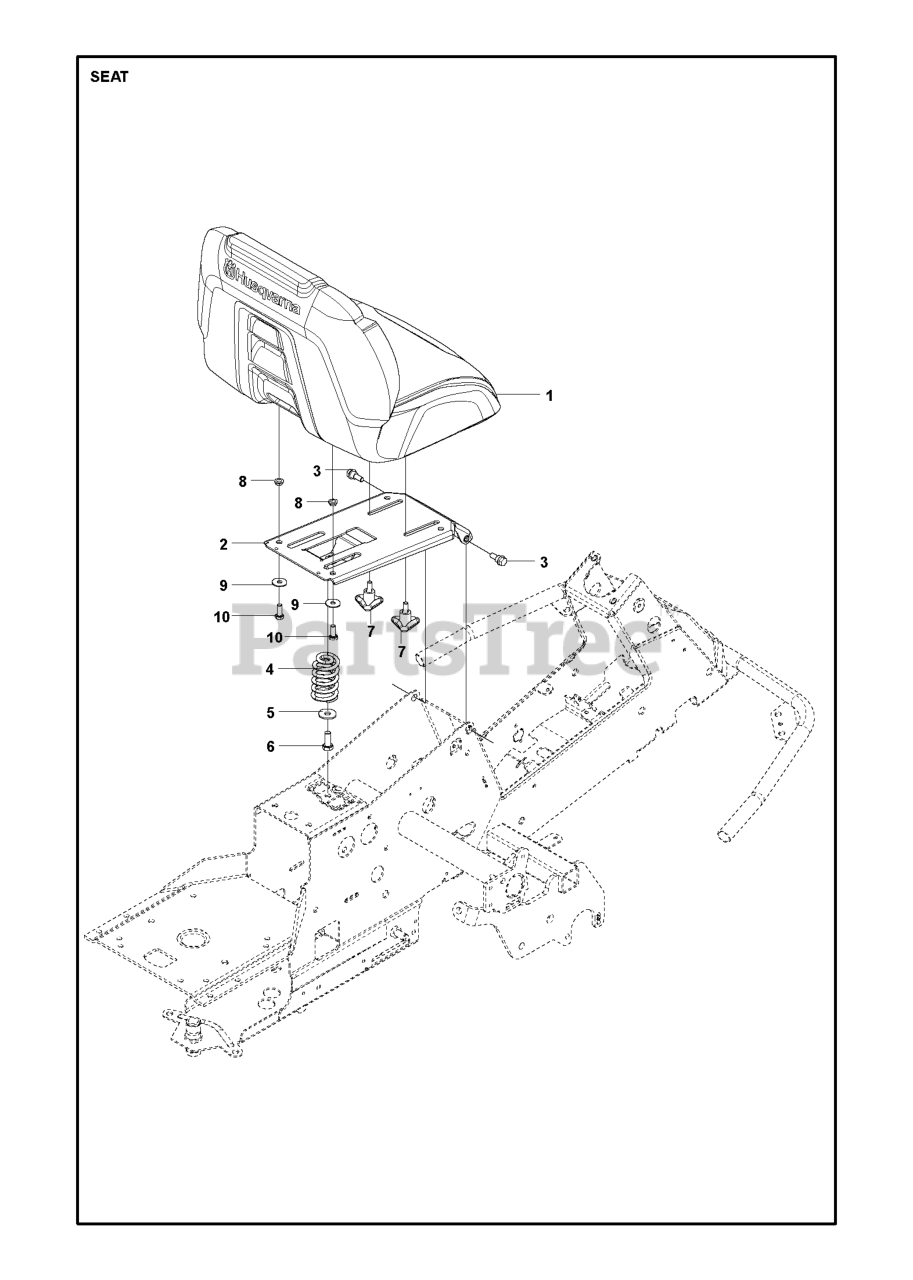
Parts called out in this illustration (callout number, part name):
1	SEAT HUSQVARNA LOW BACK
2	SEAT BRACKET ASSY
4	SEAT SPRING
6	Screw M10x25
